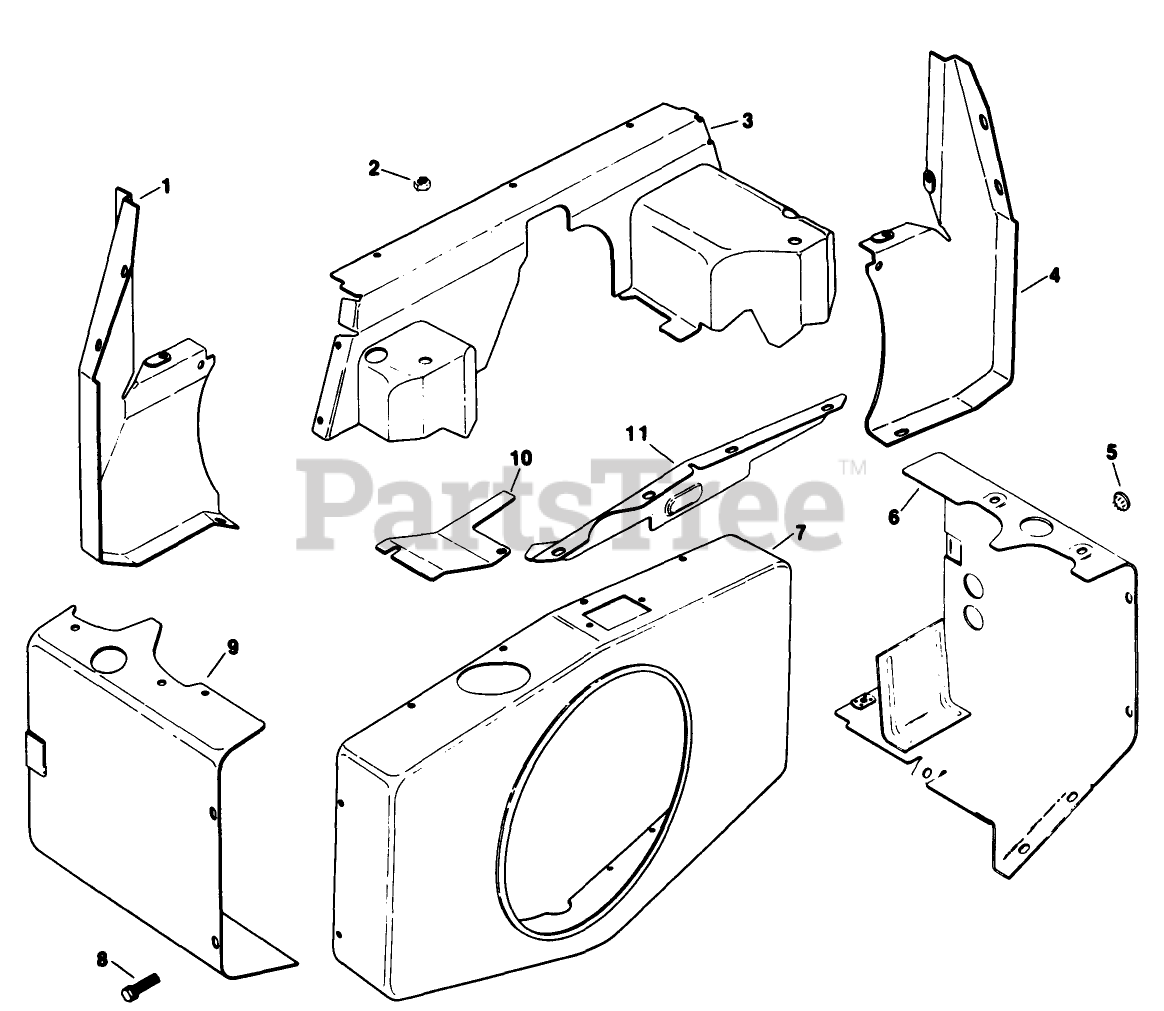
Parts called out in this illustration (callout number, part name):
1	Duct-#2 Side, Air
2	Nut
3	Cover-Air Duct
4	#1 Side-Air Duct
5	Button-Plug
6	Baffle-#1 Cylinder Head
7	Housing Blower
8	Screw
9	Baffle-Cylinder Head
10	Baffle-Cylinder Head
11	Support-Upper Housing
